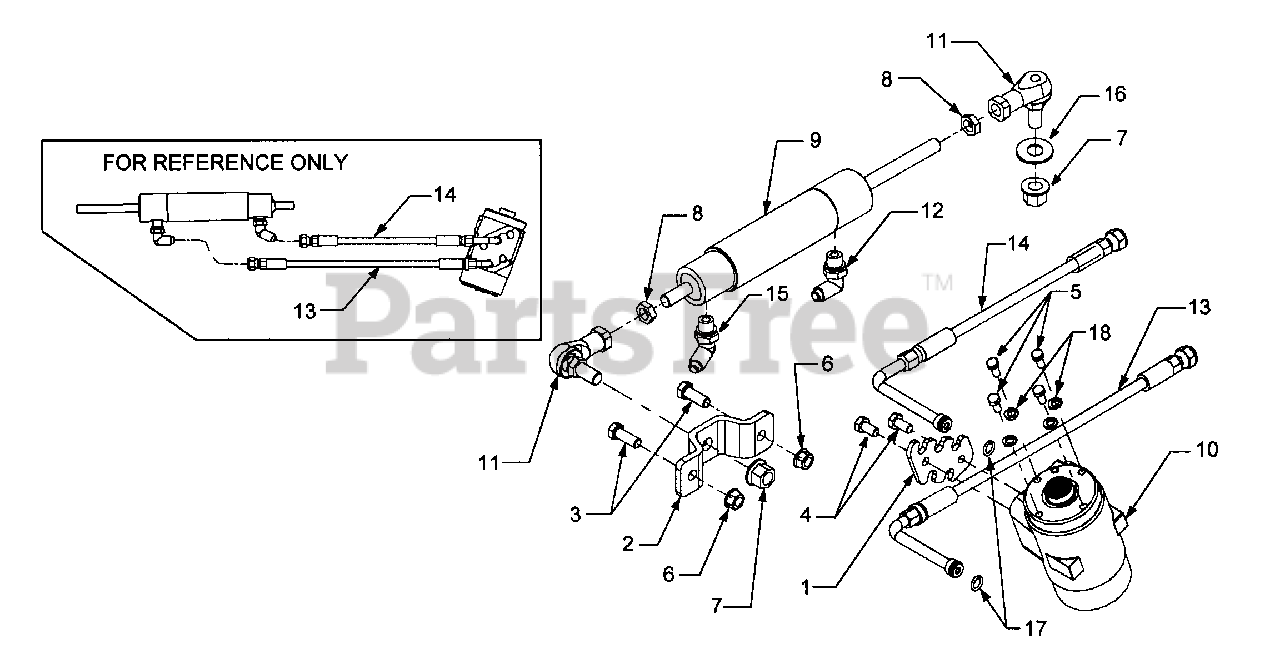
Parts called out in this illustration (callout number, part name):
3	Screw, Hex Cap 3/8-16 x 1.0 GR5
4	Screw, Hex Cap M8-1.25 x 16MM GR5
5	Screw, Hex Cap, M6 x 14MM
6	Nut, Hex Flange Lock, 3/8-16
7	Nut, Hex Flange Lock, M12 x 1.75
8	Nut, Hex, M12 x 1.75 RH
9	Cylinder, Steering
10	Pump, Hydraulic Steering
11	Ball Joint, 12MM x 1.75 RH
12	Fitting, 90 Degree Elbow
13	Hose, Front Steering
14	Hose, Rear Steering
15	Fitting, 45 Degree
16	Washer, Flat, .51 x 1.12 x .060
17	O-Ring, .426 x .566 x .070
18	Washer, Lock, 1/4"
